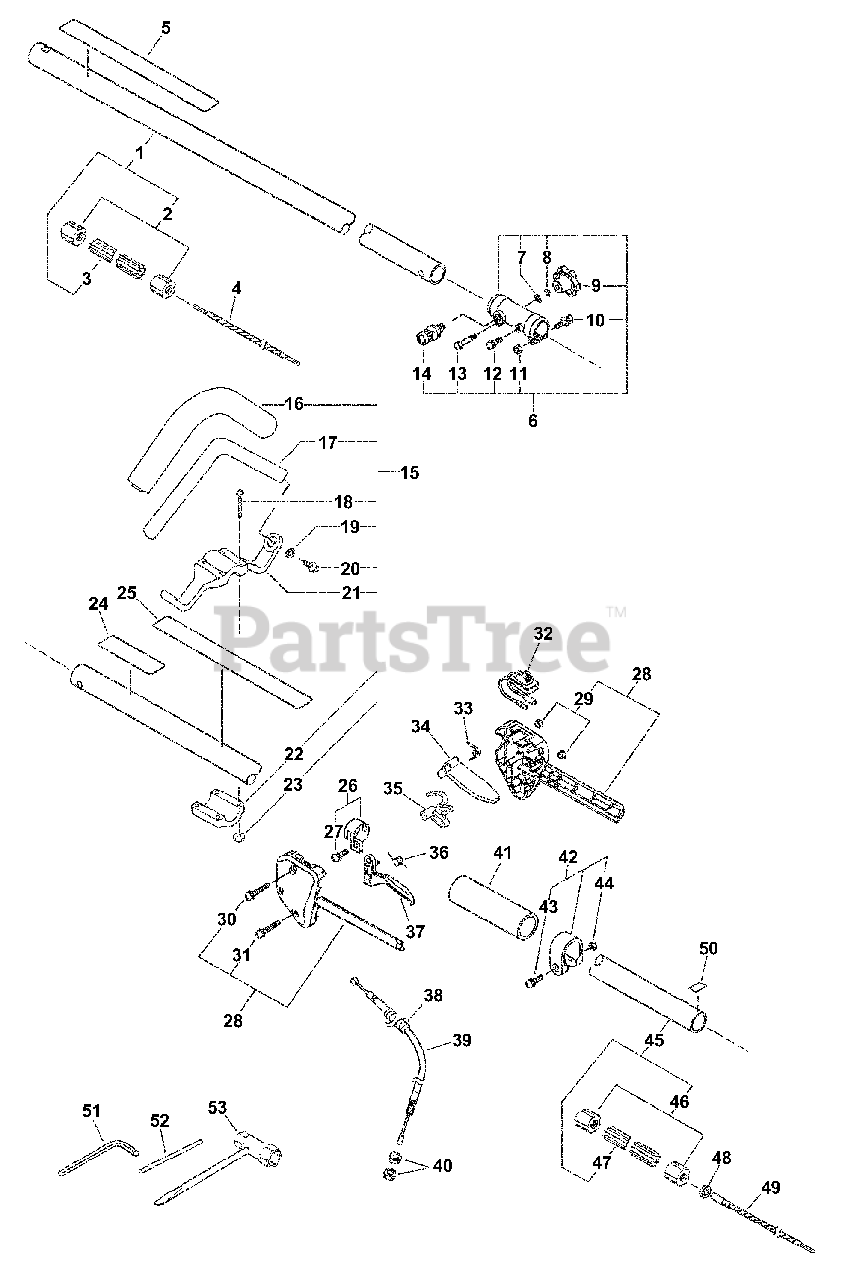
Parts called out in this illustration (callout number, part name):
1	MAIN PIPE ASSY
3	LINER - FLEXIBLE
4	DRIVESHAFT - FLEXIBLE
5	LABEL - CAUTION
6	COUPLER ASSY
7	WASHER - 5
8	LOCKWASHER - 5
9	KNOB, FASTENER
10	SCREW - 5X30
12	SCREW - 5X12
13	BOLT - 5X35
14	LATCH ASSY
15	HANDLE ASSY - FRONT
16	GRIP, HANDLE
17	HANDLE - FRONT
18	SCREW - 5X35
19	WASHER - 5
20	SCREW - 5X20
21	BRACKET, HANDLE - UPPER
22	BRACKET, HANDLE - LOWER
24	LABEL - CAUTION -- SPANISH
25	LABEL - CAUTION
26	CLAMP KIT
27	SCREW - 5X14
28	CONTROL HANDLE KIT
30	SCREW - 5X35
31	SCREW - 5X25
32	IGNITION SWITCH ASSY
33	SPRING, LOCKOUT LEVER
34	LEVER, TRIGGER LOCKOUT
35	LOCKOUT, THROTTLE
36	SPRING, TRIGGER
37	TRIGGER, THROTTLE
38	TUBE, PROTECTIVE - CORRUGATED
39	CABLE, THROTTLE
41	GRIP, HANDLE
42	CLAMP KIT
43	SCREW - 5X28
45	MAIN PIPE ASSY
47	LINER - FLEXIBLE
49	DRIVESHAFT - FLEXIBLE -- UPPER
50	LABEL - ALIGNMENT
51	HEX KEY - 4mm
52	LOCKING TOOL
53	T-WRENCH - 17X19mm
